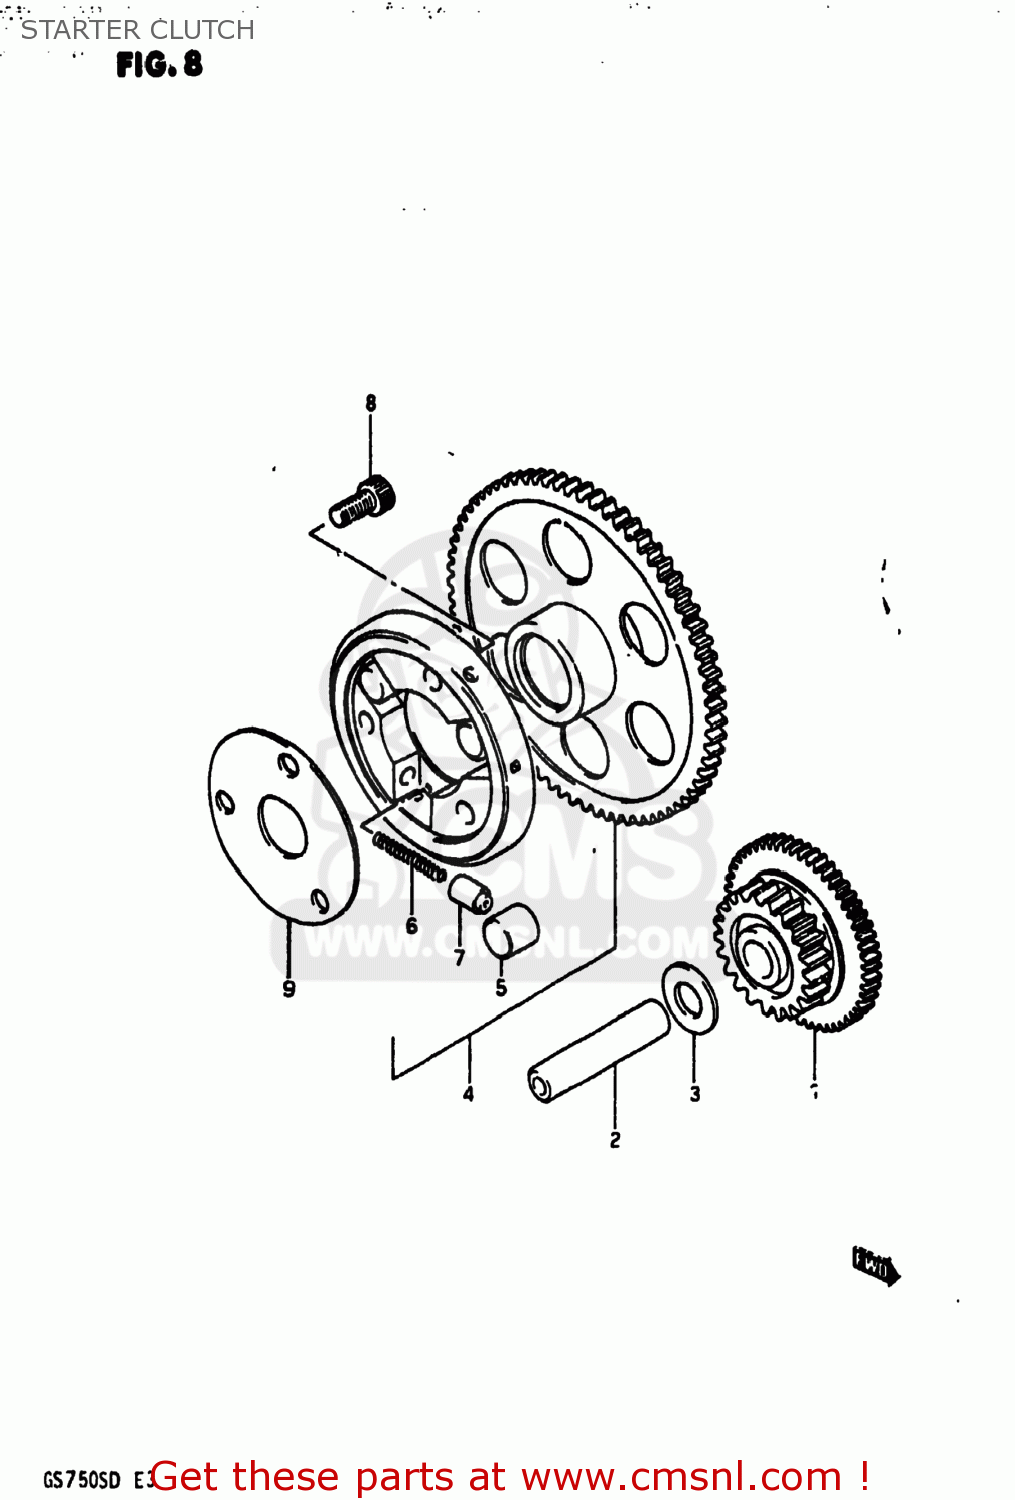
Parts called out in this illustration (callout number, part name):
1	GEAR,STARTER IDLE
2	PIN(7.4X13X56)
3	WASHER
4	CLUTCH SET,STARTER
5	ROLLER(15X13)
6	SPRING
7	PIECE,PUSH
8	BOLT
9	SHIM,STARTER CLUTCH HUB
